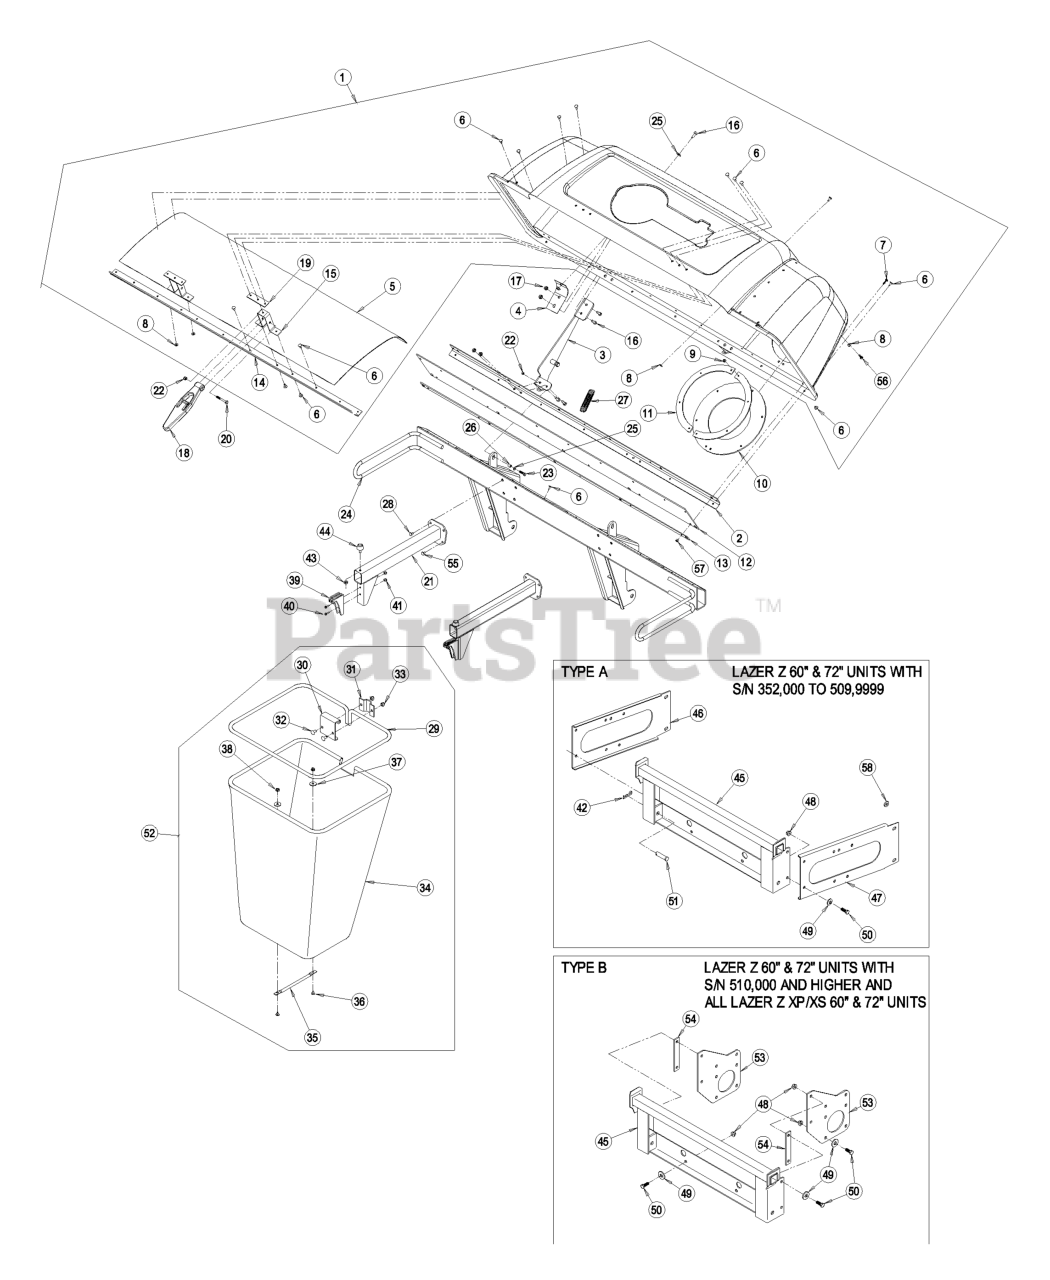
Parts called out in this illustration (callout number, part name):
1	ASM, HOOD
2	STIFFENER-BAGGER, TOP
3	HINGE ASM
4	REINFORCEMENT-HOOD, BAGGE
5	SCREEN-BAGGER
6	RIVET-BLIND
7	SCREW-HEAD, TRUSS
8	WASHER-FLAT
9	NUT-LOCK, NI
10	SEAL-TUBE
11	CLAMP-SEAL
12	SEAL-HINGE
13	PLATE-BACKING
14	SUPPORT-SCREEN
15	BRACKET-MOUNT
16	SCREW-HH
19	PLATE-LATCH, REINFORCEMEN
20	SCREW-HH
21	SUPPORT-BAG
22	NUT-LOCK, NI
23	SCREW-HH
24	UPRIGHT BAGGER ASM
25	WASHER-FLAT
27	SPRING-EXTENSION
28	SCREW-HH
29	FRAME-BAG
30	HANGER-BAG
32	BOLT-CARR
33	NUT-LOCK, NI
35	HANDLE-BAG
36	BOLT-CARR
38	NUT-LOCK, NI
40	SCREW-PPH
42	PIN-COTTER
45	MOUNT-BAGGER
46	BRACKET-FRAME, LH
47	BRACKET-FRAME, RH
48	NUT-HHF, WHIZ
49	WASHER-BELLEVILLE
50	SCREW-HH
51	PIN-CLEVIS
53	PLATE-MOUNT, BAGGER
55	SCREW-HSBH
56	SCREW-PPH
57	NUT-LOCK, SIDE
58	SPACER
